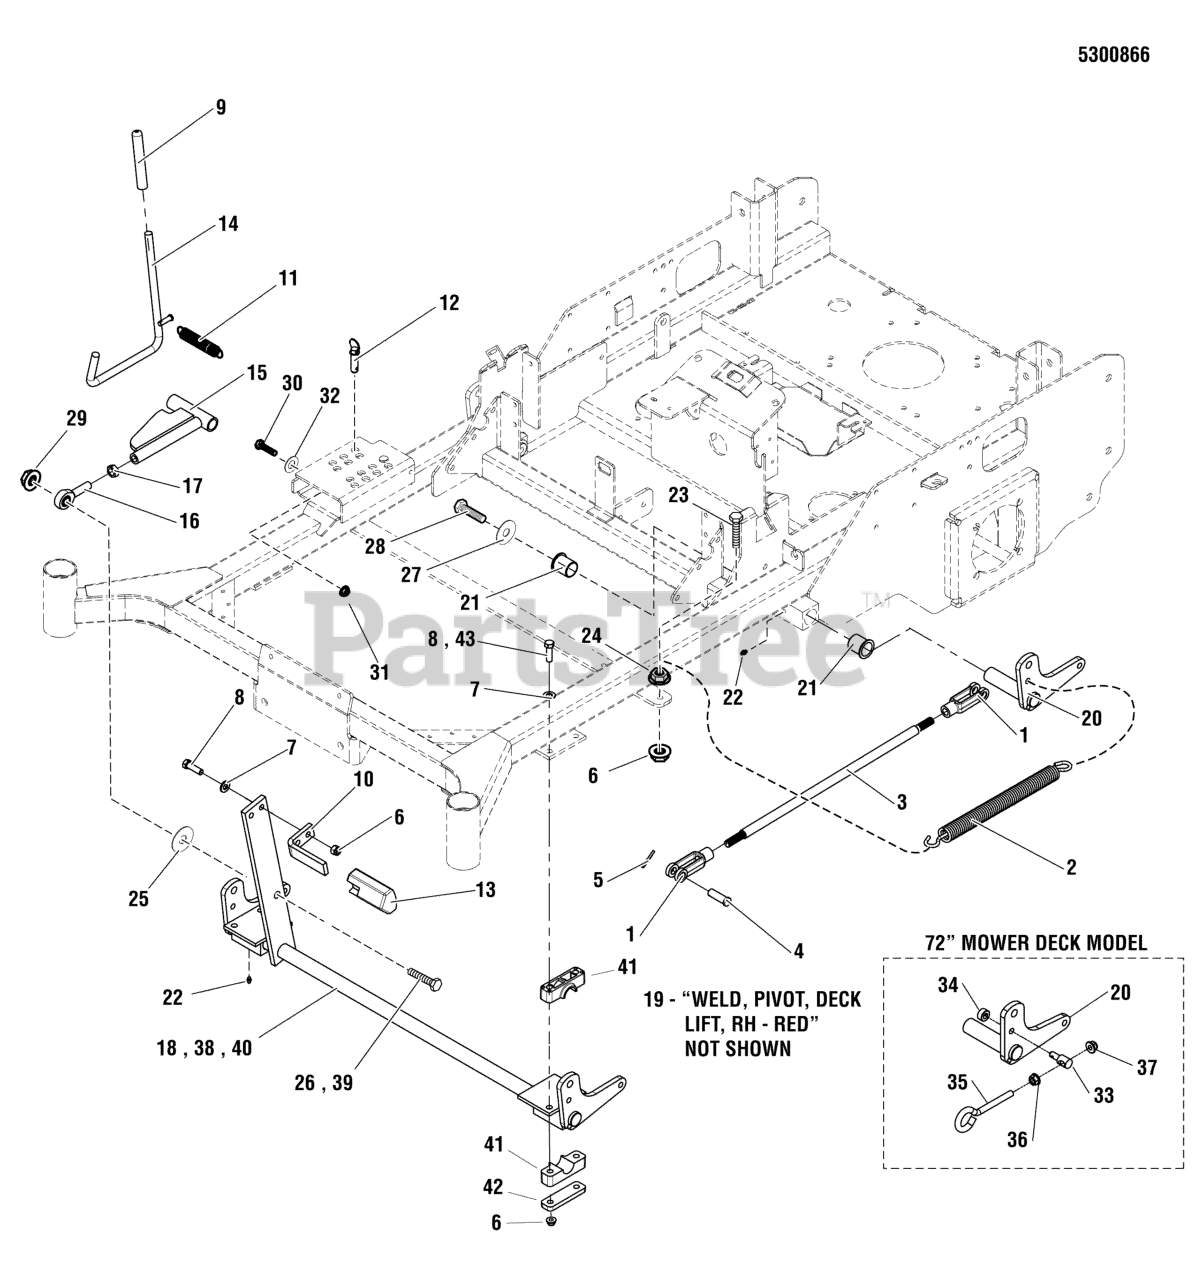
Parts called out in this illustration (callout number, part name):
1	CLEVIS, 1/2-20, STEEL
2	SPRING, DECK LIFT ASSIST
3	ROD, DECK LIFT, TWR
4	PIN, CLEVIS, 1/2 X 1 1/2, YZP
5	PIN, COTTER, 1/8" X 3/4
6	NUT, 3/8-16 HEX NYLOCK FLANGE
7	WASHER, 3/8 SAE
8	BOLT, 3/8-16 X 1-1/4" GD5 CZ
9	GRIP, FOAM
10	PEDAL, FOOT - BLK
11	SPRING, EXTENSION
12	PIN, HITCH, 1/2 X 2.00 OAL, YP
13	PEDAL, Rubber
14	WELD, ROD DECK LIFT - BLK
15	WELD, DECK ADJUST LINK - SNP RED
16	BALL JOINT, 1/2-20, MALE
17	NUT, 1/2-20 HEX JAM
18	WELD, DECK LIFT SHAFT - RED
19	WELD, PIVOT, DECK LIFT, RH - RED
20	WELD, PIVOT, DECK LIFT, LH - RED
21	BUSHING, 1.00 X 1.13 X 1.38, PLASTIC
22	GREASE FITTING, 1/4-28 STRAIGHT
23	BOLT, 3/8-16 X 1-1/2" GD5 CZ
24	NUT, 3/8-16 HEX SERRATED FLANGE
25	WASHER, 1/2 SAE
26	BOLT, 1/2-13 X 2" GD5 CZ
27	WASHER, .390 X 1.50 X .109, YZ
28	BOLT, 3/8-16 X 3/4, GD5, YZ WITH PATCH
29	NUT, Hex Flange, Nylock, 1/2-13
30	BOLT, 5/16-18 X 3/4 GD5
31	NUT, 5/16-18 HEX NYLOCK FLANGE
32	WASHER, 5/16" SAE
33	ADJUSTER, DECK HANGER
34	COLLAR, 3/8 SET
35	EYE BOLT, 3/8-16 X 5, 2.88THRD, 1EYE, CZ
36	NUT, 3/8-16 HEX SERRATED FLANGE
37	NUT, 3/8-16 HEX NYLOCK FLANGE
38	WELD, DECK LIFT SHAFT - SNAPPER RED
39	BOLT, 1/2-13 X 2-1/4" GD5 CZ
40	WELD, DECK LIFT SHAFT - RED
41	PIVOT BLOCK, PLASTIC
42	PLATE, PIVOT BLOCK SUPPORT - BLK
43	BOLT, 3/8-16 X 2-3/4" GD5 CZ
